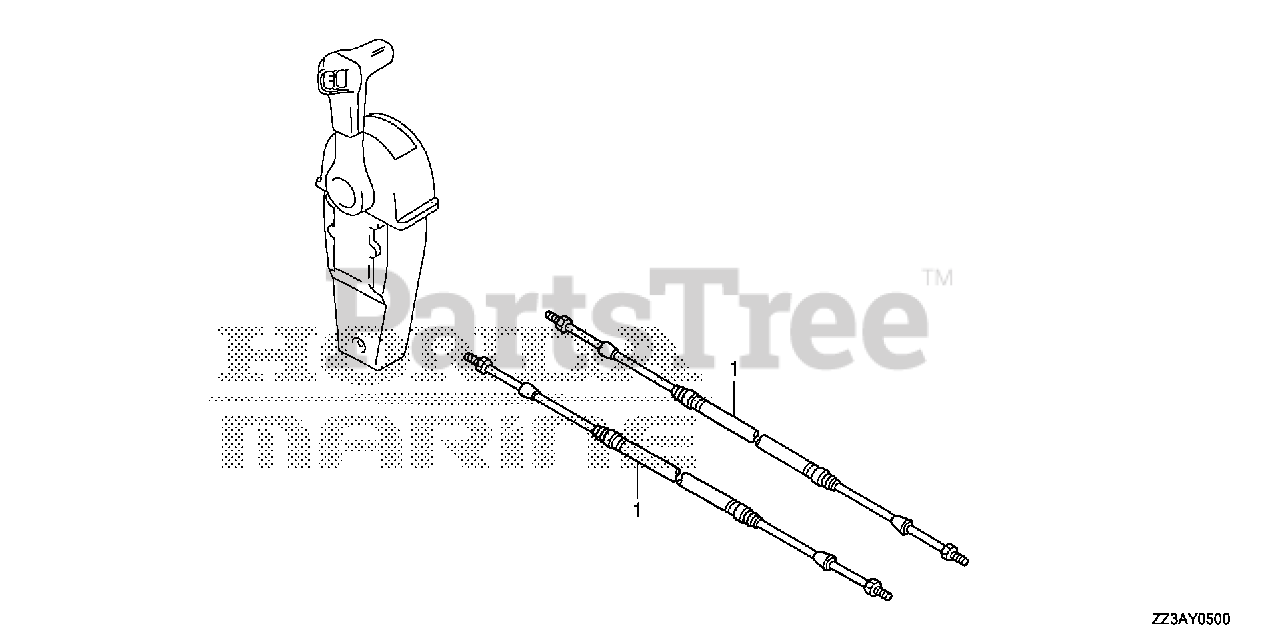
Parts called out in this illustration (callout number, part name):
1	CABLE, REMOTE CONTROL (10') (LOW FRICTION)
1	CABLE ASSY., PUSH-PULL (33C-5FT)
1	CABLE, REMOTE CONTROL (11') (LOW FRICTION)
1	CABLE ASSY., PUSH-PULL (33C-6FT)
1	CABLE, REMOTE CONTROL (12') (LOW FRICTION)
1	CABLE ASSY., PUSH-PULL (33C-7FT)
1	CABLE, REMOTE CONTROL (13') (LOW FRICTION)
1	CABLE ASSY., PUSH-PULL (33C-8FT)
1	CABLE, REMOTE CONTROL (14') (LOW FRICTION)
1	CABLE ASSY., PUSH-PULL (33C-9FT)
1	CABLE, REMOTE CONTROL (15') (LOW FRICTION)
1	CABLE ASSY., PUSH-PULL (33C-10FT)
1	CABLE, REMOTE CONTROL (16') (LOW FRICTION) (NOT AVAILABLE)
1	CABLE ASSY., PUSH-PULL (33C-11FT)
1	CABLE, REMOTE CONTROL (17') (LOW FRICTION)
1	CABLE ASSY., PUSH-PULL (33C-12FT)
1	CABLE, REMOTE CONTROL (18') (LOW FRICTION) (NOT AVAILABLE)
1	CABLE ASSY., PUSH-PULL (33C-13FT)
1	CABLE, REMOTE CONTROL (19') (LOW FRICTION)
1	CABLE ASSY., PUSH-PULL (33C-14FT)
1	CABLE, REMOTE CONTROL (20') (LOW FRICTION) (NOT AVAILABLE)
1	CABLE ASSY., PUSH-PULL (33C-15FT)
1	CABLE, REMOTE CONTROL (21') (LOW FRICTION)
1	CABLE ASSY., PUSH-PULL (33C-16FT)
1	CABLE, REMOTE CONTROL (22') (LOW FRICTION) (NOT AVAILABLE)
1	CABLE ASSY., PUSH-PULL (33C-17FT)
1	CABLE, REMOTE CONTROL (23') (LOW FRICTION)
1	CABLE ASSY., PUSH-PULL (33C-18FT)
1	CABLE, REMOTE CONTROL (24') (LOW FRICTION) (NOT AVAILABLE)
1	CABLE ASSY., PUSH-PULL (33C-19FT)
1	CABLE, REMOTE CONTROL (25') (LOW FRICTION)
1	CABLE ASSY., PUSH-PULL (33C-20FT)
1	CABLE, REMOTE CONTROL (26') (LOW FRICTION)
1	CABLE ASSY., PUSH-PULL (33C-21FT)
1	CABLE, REMOTE CONTROL (27') (LOW FRICTION)
1	CABLE ASSY., PUSH-PULL (33C-22FT)
1	CABLE, REMOTE CONTROL (28') (LOW FRICTION) (NOT AVAILABLE)
1	CABLE ASSY., PUSH-PULL (33C-23FT)
1	CABLE, REMOTE CONTROL (29') (LOW FRICTION)
1	CABLE ASSY., PUSH-PULL (33C-24FT)
1	CABLE, REMOTE CONTROL (30') (LOW FRICTION) (NOT AVAILABLE)
1	CABLE ASSY., PUSH-PULL (33C-25FT)
1	CABLE, REMOTE CONTROL (31') (LOW FRICTION)
1	CABLE ASSY., PUSH-PULL (33C-26FT)
1	CABLE, REMOTE CONTROL (32') (LOW FRICTION) (NOT AVAILABLE)
1	CABLE ASSY., PUSH-PULL (33C-27FT)
1	CABLE, REMOTE CONTROL (33') (LOW FRICTION)
1	CABLE ASSY., PUSH-PULL (33C-28FT)
1	CABLE, REMOTE CONTROL (34') (LOW FRICTION) (NOT AVAILABLE)
1	CABLE ASSY., PUSH-PULL (33C-29FT)
1	CABLE, REMOTE CONTROL (35') (LOW FRICTION)
1	CABLE ASSY., PUSH-PULL (33C-30FT)
1	CABLE ASSY., PUSH-PULL (33C-31FT)
1	CABLE ASSY., PUSH-PULL (33C-32FT)
